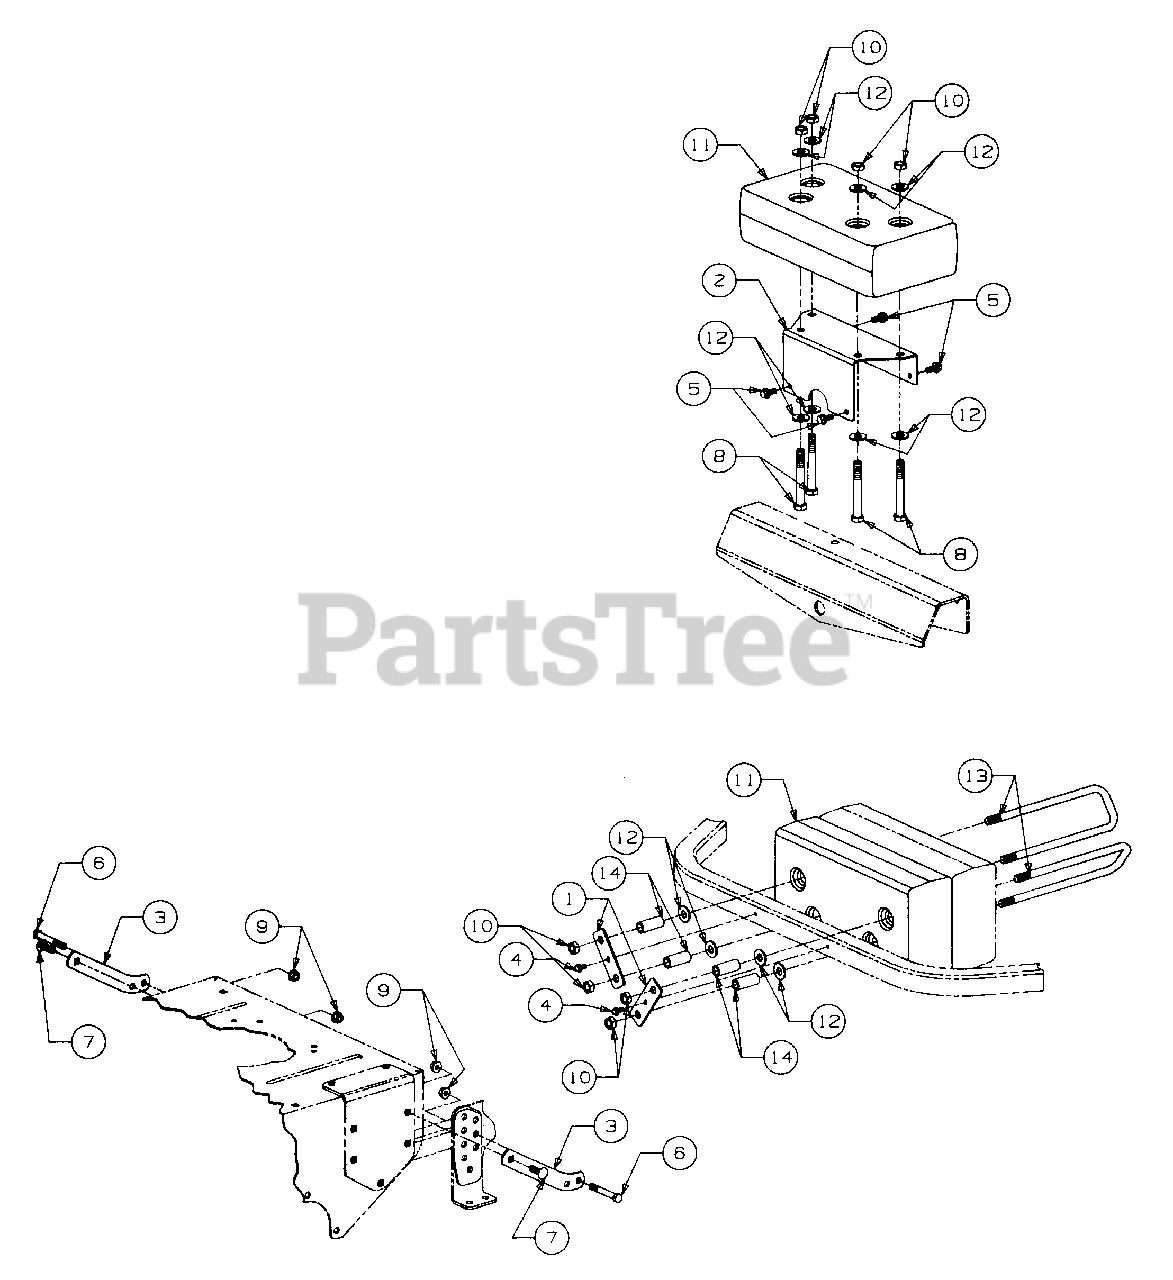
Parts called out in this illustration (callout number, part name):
3	Strap, Cradle Reinforcement
4	Screw, Hex Wash TT-Tap, 1/4-20 X .50 Lg
5	Screw, Hex Wash TPTT, 5/16-18 X .75 Lg
6	Screw, Hex Cap, 3/8-16 X 2.7 Lg GR5
7	Bolt, Carriage, 3/8-16 X 1.25 Lg GR5
8	Screw, Hex Cap, 1/2-20 X 4.0 Lg GR5
9	Nut, Hex Flanged Lock, 3/8-16
10	Nut, Hex Top Lock Jam, 1/2-20 GR5
11	Weight, Counter, 38 Lbs
12	Washer, Flat, .515 X 1.12 X .100 Thk Hdn
13	U-Bolt, Weight Mtg
14	Spacer, .505 ID X .750 OD X 1.75 Lg
